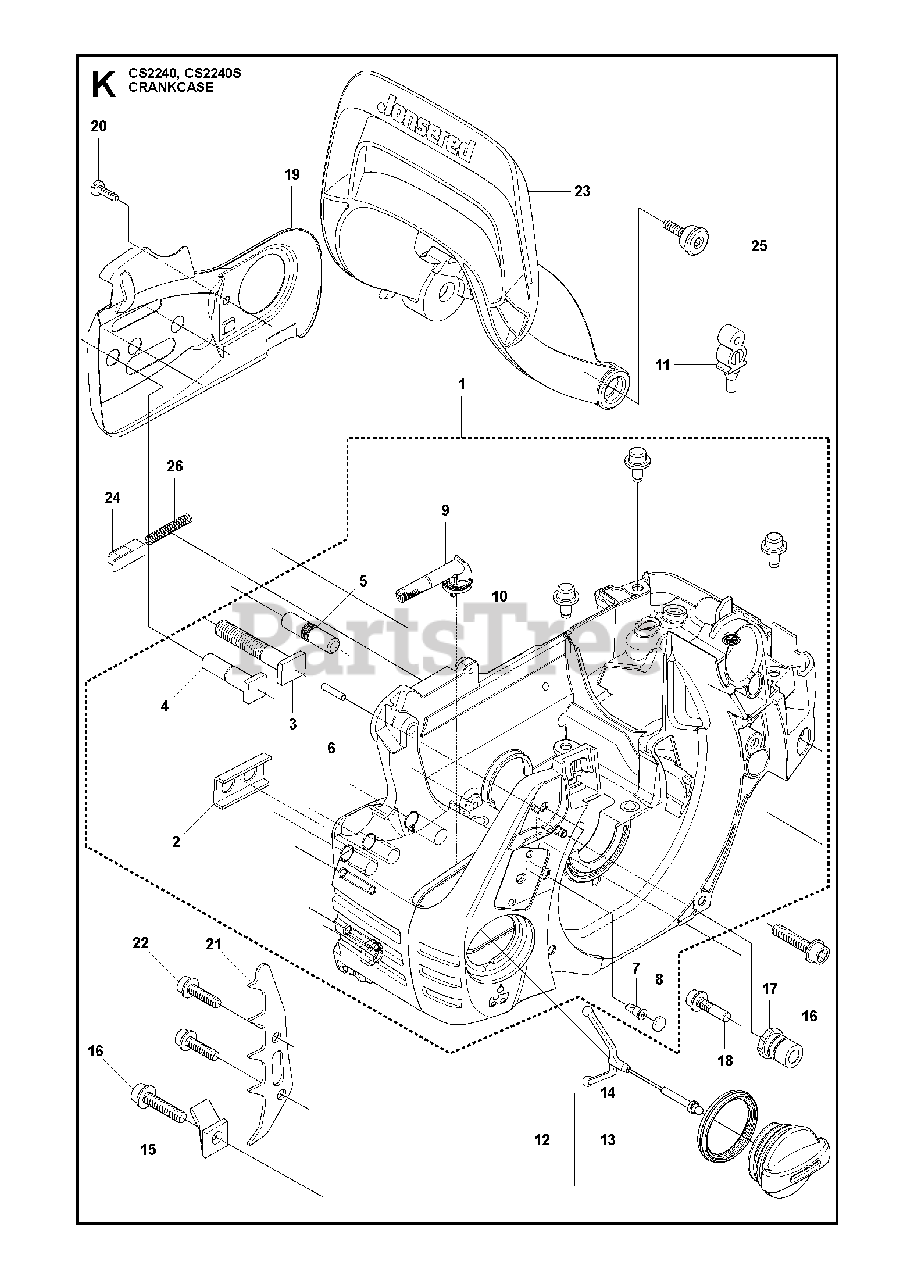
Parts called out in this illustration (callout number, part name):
1	CRANKCASE ASSY
2	STIFFENING PLATE
3	BAR BOLT
4	BAR BOLT (X2)
5	BAR BOLT
6	PIN
7	VALVE-CHECK (DUCKBILL)
8	PLUG
9	OIL SCREEN
10	GUIDE PEN
12	TANK CAP ASSY
13	SEALING
14	HOLDER
15	CHAIN CATCHER
17	LATERAL SUPPORT
18	SCREW IHSCFT
19	CHAIN GUIDE PLATE
21	SPIKE INNER
23	HAND GUARD
26	LOCK SPRING
